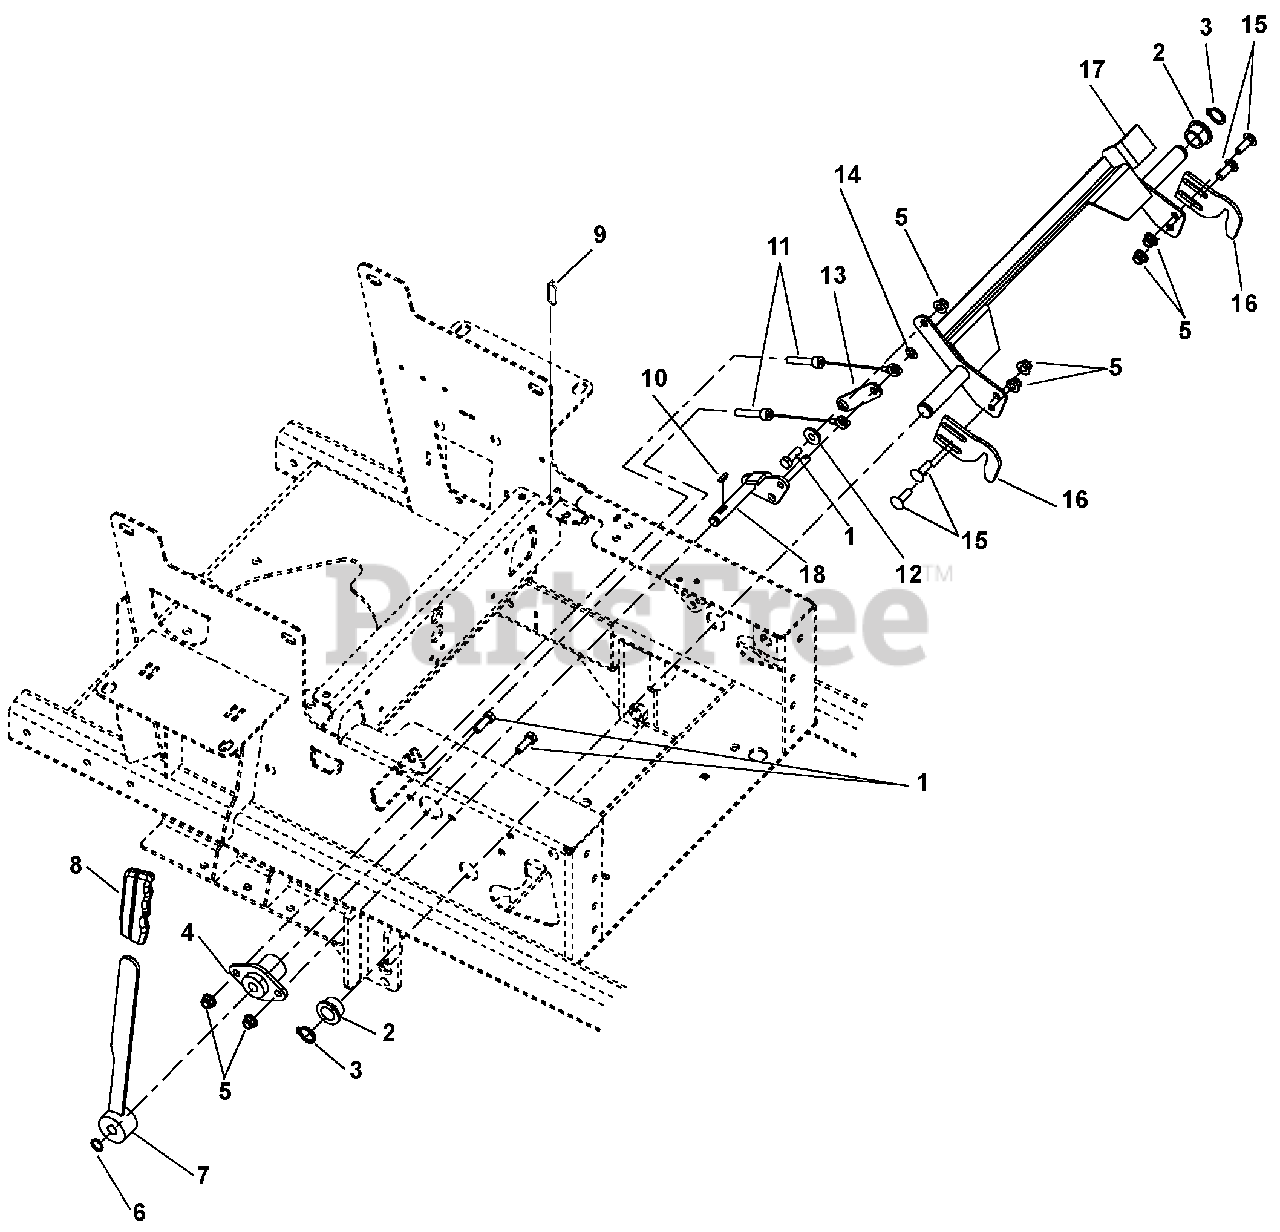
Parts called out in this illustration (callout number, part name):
1	Bolt, Hex .31-18 x 1.00
2	Bushing, Flange .750 x 1.000 x .625 x 1.250
3	Ring, Retaining-External .689 x .077
4	Bushing, Flanged
5	Nut, .31-18 Nyloc Flange
6	Ring, Retaining-External .500 x .050
7	Weldment, Parking Brake Arm
8	Grip, Parking Brake
9	Cable Tie
10	Key, Woodruff .13 x .63 HRD #5
11	Cable, Brake Actuating
12	Bushing, Flange .325 x .499 x .26 x .88
13	Plate, Neutral Interlock
14	Nut, Push .312
15	Bolt, Round Head Square Neck .31-18 x 1.00
16	Neutral Lock Latch
17	Weldment, 100I Neutral Lock
18	Weldment, Park Brake Arm
